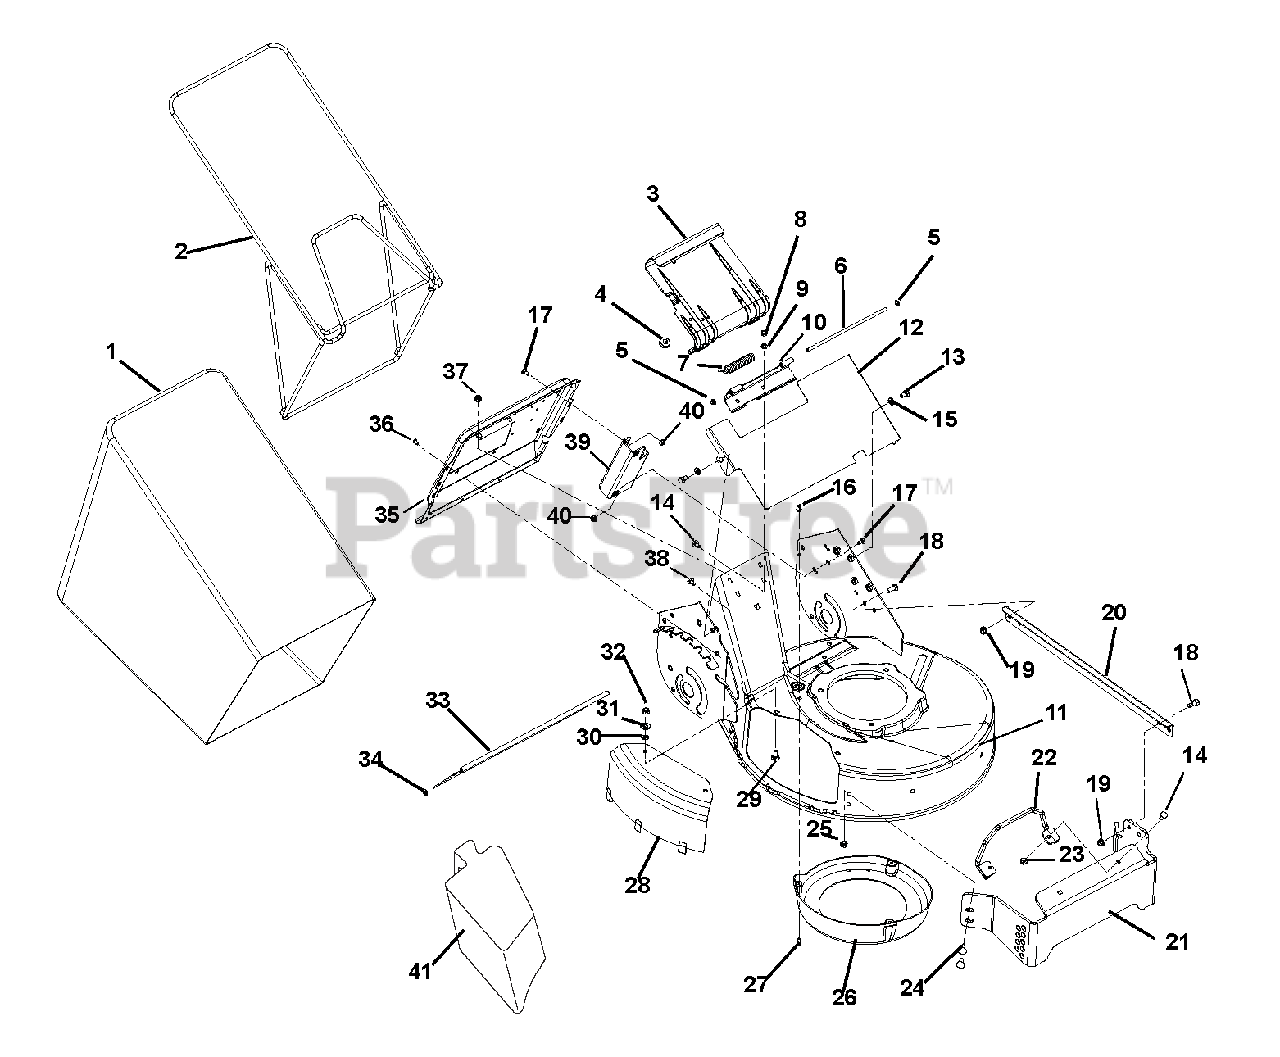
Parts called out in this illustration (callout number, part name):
1	BAG, CONSUMER BLACK 15 OZ/YD2
2	FRAME, WBLM BAGGER
3	CATCHER PLATE DOOR
4	BUTTON BUMPER
5	PUSH NUT, .25
6	DOOR PIN
7	SG-TORS .120X.68X3.09
8	@NUT-HEX .25-20 YWZC
9	WSHR-LK .250X.077 HVY YWZC
10	HINGE BASE
11	CHASSIS,PRO 21 XD
12	COVER
13	@SCR-TAP .25-20X.37 HWH YWZ TR
14	@BLT-RDHDSQNK .25-20X.75 G5YZ
15	@WSHR-LK .31X.078 REG YWZC
16	PLASTIC GROMMET
17	@BLT-RDHDSQNK .25-20X.50 G5YZ
18	@BLT-HEX .31-18X.75 GR5 YWZC
19	@NUT-LK-TOP-FLG .31-18 YWZC
20	ANGLE-SUPPORT
21	BUMPER,PRO 21"
22	ANGLE-SUPPORT
23	@NUT-LK-TOP-FLG .25-20 YWZC
24	@BLT-RDHDSQNK .31-18X.75 G5YZ
25	@NUT-SPNLK-FLG .312-18 YWZC
26	CENTER BAFFLE
27	SCR-TAP 10-16X.62 SLPH AB YWZC
28	COVER, SIDE DISCHARGE
29	BLT-RDHDSQSHK.31-18X.75 GR2 YW
30	NUT-PUSH .312
31	@WSHR-FL-STL.406X.812X.065 YWZ
32	@NUT-LK-NYL .312-18 YWZC
33	TRAILING SHIELD
34	NUT-PUSH .312
35	CATCHER PLATE
36	SCR-TAP 10-24X.375 TORX PHD YZ
37	@NUT-SPNLK-FLG .25-20 YWZC
38	@BLT-RDHDSQNK .25-20X.50 G5YZ
39	BKT,BAGGER SUPPORT
40	@NUT-SPNLK-FLG .25-20 YWZC
41	MULCH MASTER MULCHER ACCESSORY
